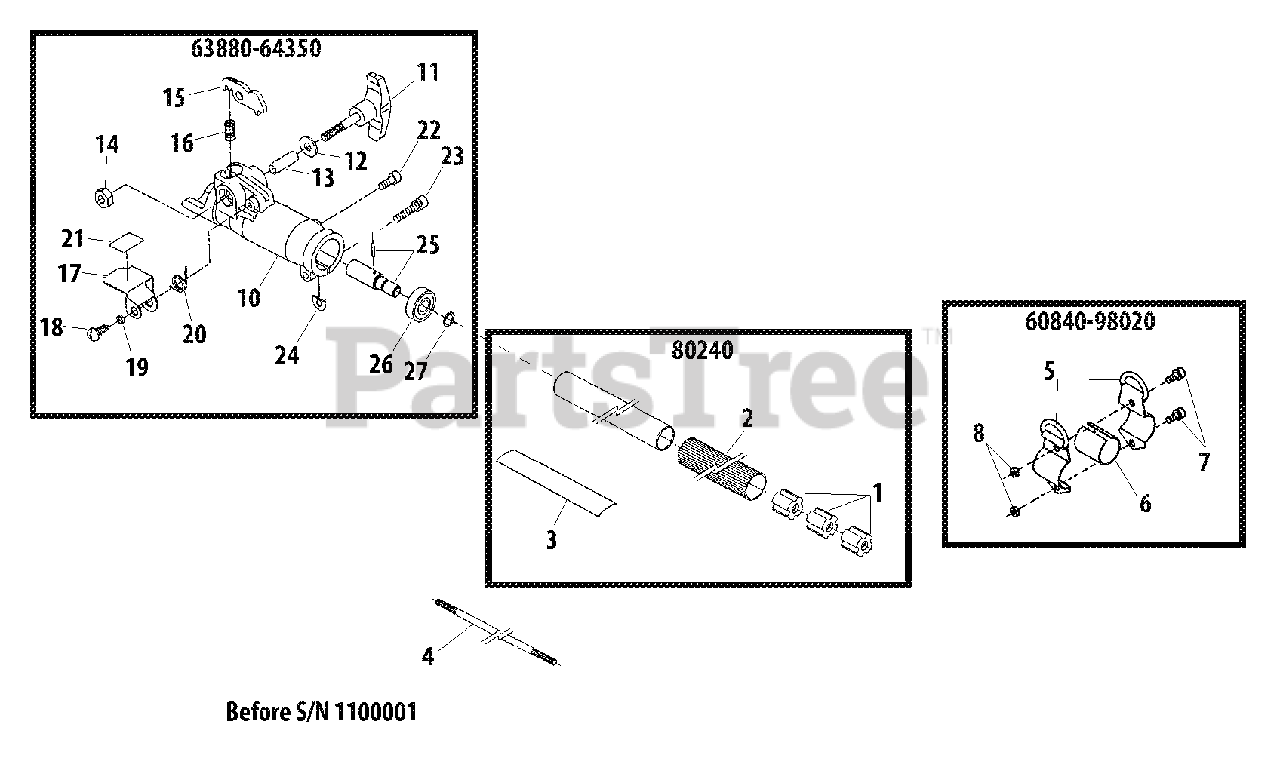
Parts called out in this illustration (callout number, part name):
1	BUSHING
2	GRIP
3	LABEL - CAUTION
4	MAINSHAFT
5	HANGER SET
6	SPACER
7	BOLT M5×12
8	NUT M5
10	HOUSING, COUPLER
11	KNOB, COUPLER SCREW
12	WASHER 6
13	COLLAR
14	NUT 6
15	LATCH
16	SPRING
17	PROTECTOR, LATCH
18	SCREW
19	WASHER 5
20	SPRING, TORSION
21	LABEL, LATCH INSTRUCTION
22	BOLT 5×12
23	BOLT M5×25
24	D-WASHER
25	SHAFT, COUPLER
26	BEARING, BALL 609ZZ
27	RING, SNAP
60840-98020	HANGER ASSY
63880-64350	COUPLER ASSY
80240	MAIN PIPE ASSY
